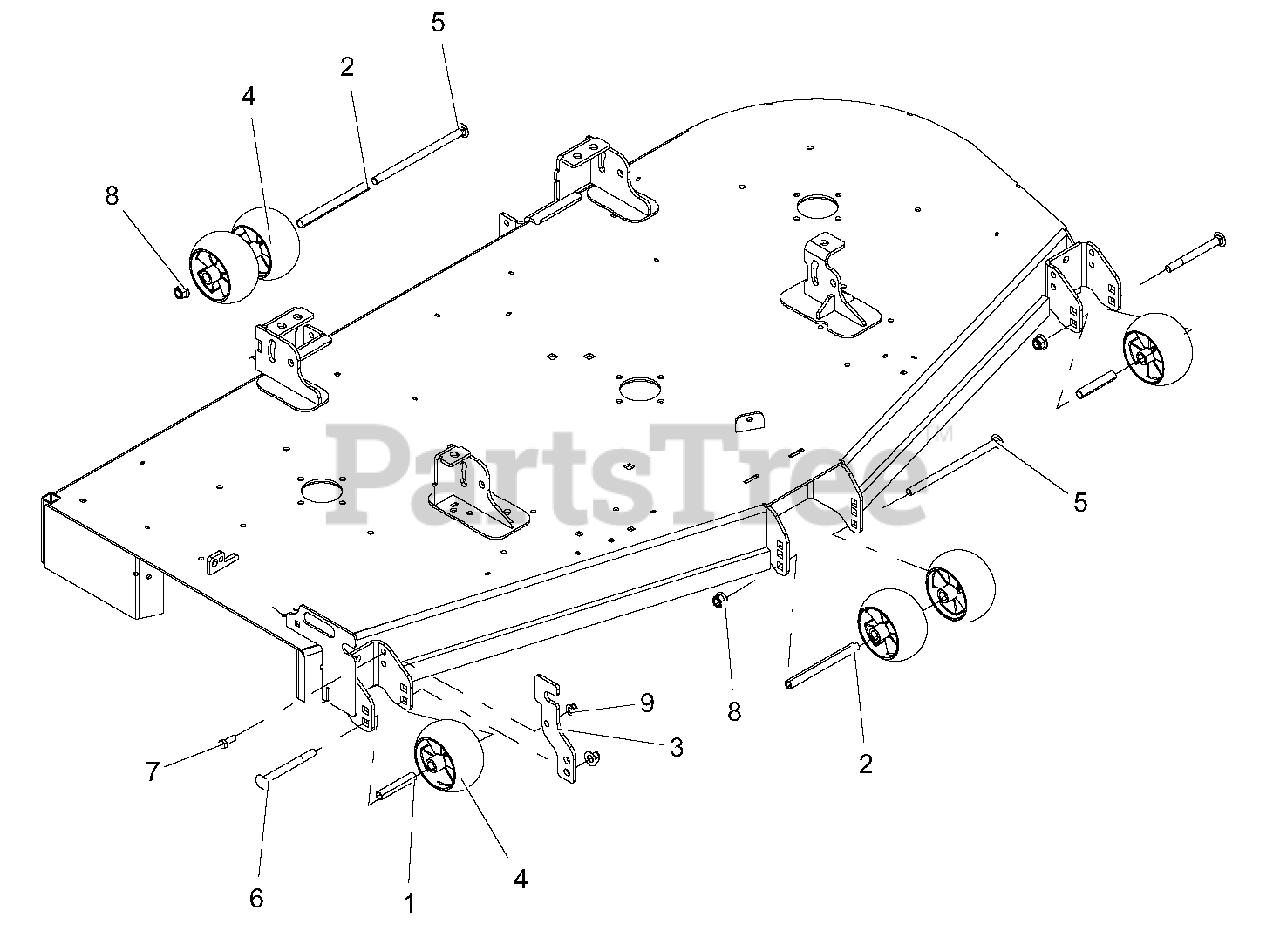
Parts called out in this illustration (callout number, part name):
1	SPACER, .510X.625X3.35
2	SPACER, .510X.625X6.70
3	CHUTE STORAGE BRACKET-RED
4	ANTI-SCALP WHEEL - 5X3 CTR
5	@BLT-RDHDSQNK .50-13X8.50 Y
6	BLT-RDHDSQNK .50-13X5.00 G5
7	BLT-HEX .38-16X1.00 GR5 YWZC
8	NUT-LK-NYL-FLG .50-13 YWZC
9	NUT-LK-NYL-FLG .38-16 YWZC
